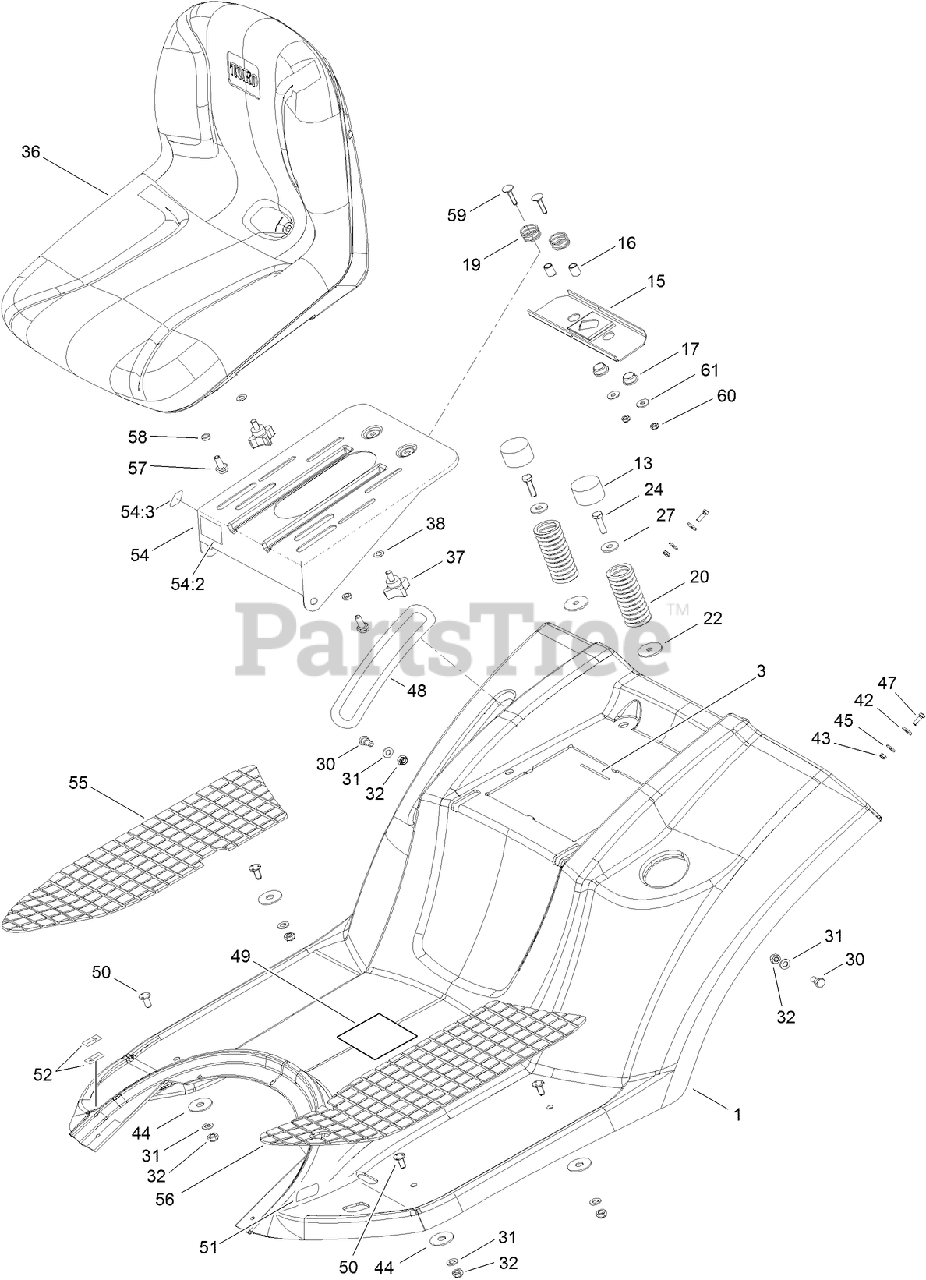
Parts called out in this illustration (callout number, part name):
1	FENDER-REAR
3	PURL-RUBBER, BATTERY
13	CAP-HUB
15	BRACKET
16	SPACER-SPLIT
17	BUSHING
19	SEAT-SPRING
20	SPRING-SEAT
22	WASHER
24	SCREW-HH
27	WASHER-PLAIN
30	SCREW-SUPPORT, SEAT
31	WASHER-PLAIN
32	NUT-LOCK, NI
37	KNOB-ADJUST
38	WASHER-SPRING
42	WASHER-FLAT
43	NUT-LOCK
44	WASHER-RUBBER
45	WASHER-RUBBER
48	DECAL-HEIGHT OF CUT
49	DECAL-DANGER
50	SCREW-HSFH
51	DECAL-BRAKE, PARKING
52	DECAL-TRAVEL
54	BRACKET-SUPPORT, SEAT
54:2	DECAL-DANGER
54:3	DECAL-SWITCH
55	MAT-FOOT, RH
56	MAT-FOOT, LH
57	SCREW-HHF
58	SPACER
60	NUT-LOCK
61	WASHER-FLAT
